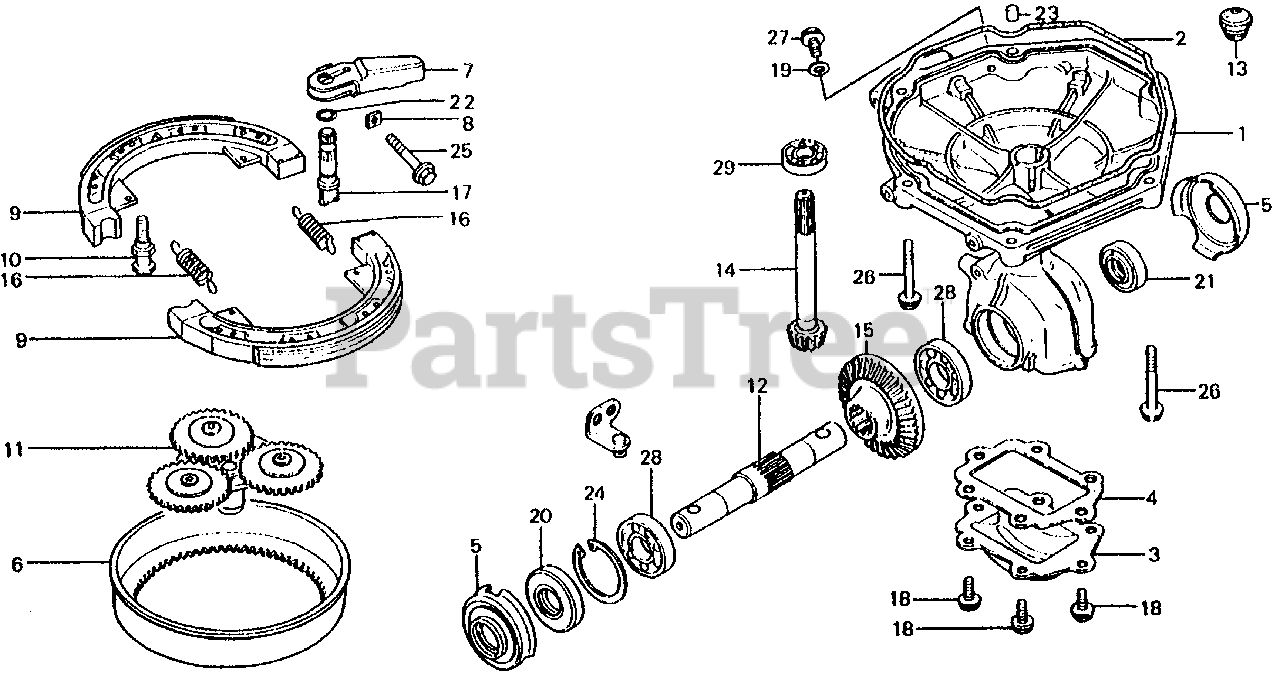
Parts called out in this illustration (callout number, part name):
1	CASE, REDUCTION
2	O-RING (208MM)
3	COVER (LOWER)
4	GASKET, COVER
5	GUARD, GRASS
6	CLUTCH (OUTER)
7	ARM, CLUTCH
8	PLATE, ARM LOCK
9	SHOE SET, CLUTCH
10	PIN, ANCHOR
11	PLATE, DRIVE
12	SHAFT, TINE
13	CAP, TRANSMISSION OIL
14	PINION, BEVEL
15	GEAR, BEVEL
16	SPRING, FR. BRAKE SHOE
17	CAM, CLUTCH
18	BOLT, SPECIAL (6X14)
19	WASHER (10.5MM)
20	OIL SEAL (20X47X7)
21	DUST SEAL (20X40X11)
22	O-RING (8.8X1.9)
23	PIN A, DOWEL (8X12)
24	CIRCLIP (INNER) (47MM)
25	BOLT, FLANGE (6X32)
26	BOLT, FLANGE (6X45)
27	BOLT, FLANGE (10X16)
28	BEARING, RADIAL BALL (6204)
29	BEARING, RADIAL BALL (6302)
